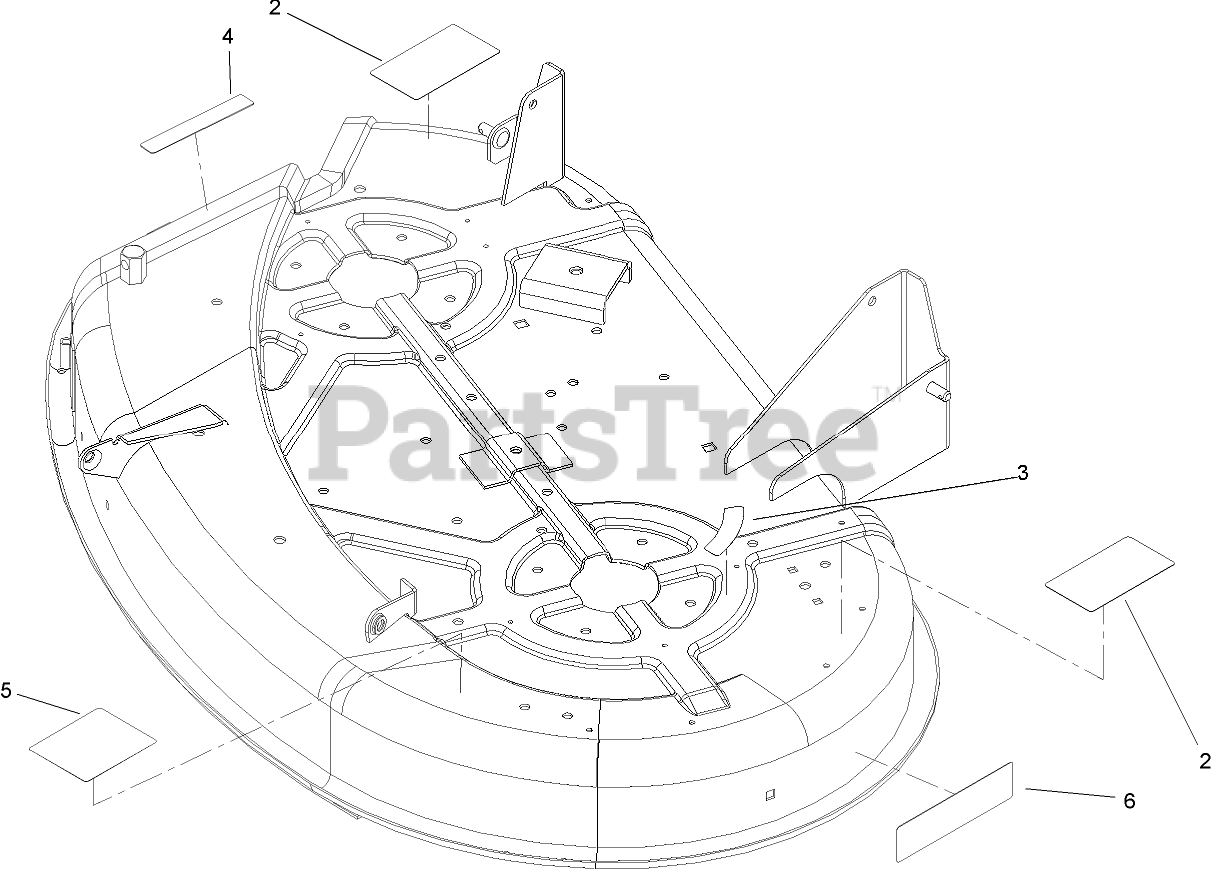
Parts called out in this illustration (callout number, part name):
2	DECAL-DANGER
3	DECAL-DANGER, SHIELD
4	DECAL-DANGER
5	DECAL-ROUTING, BELT
